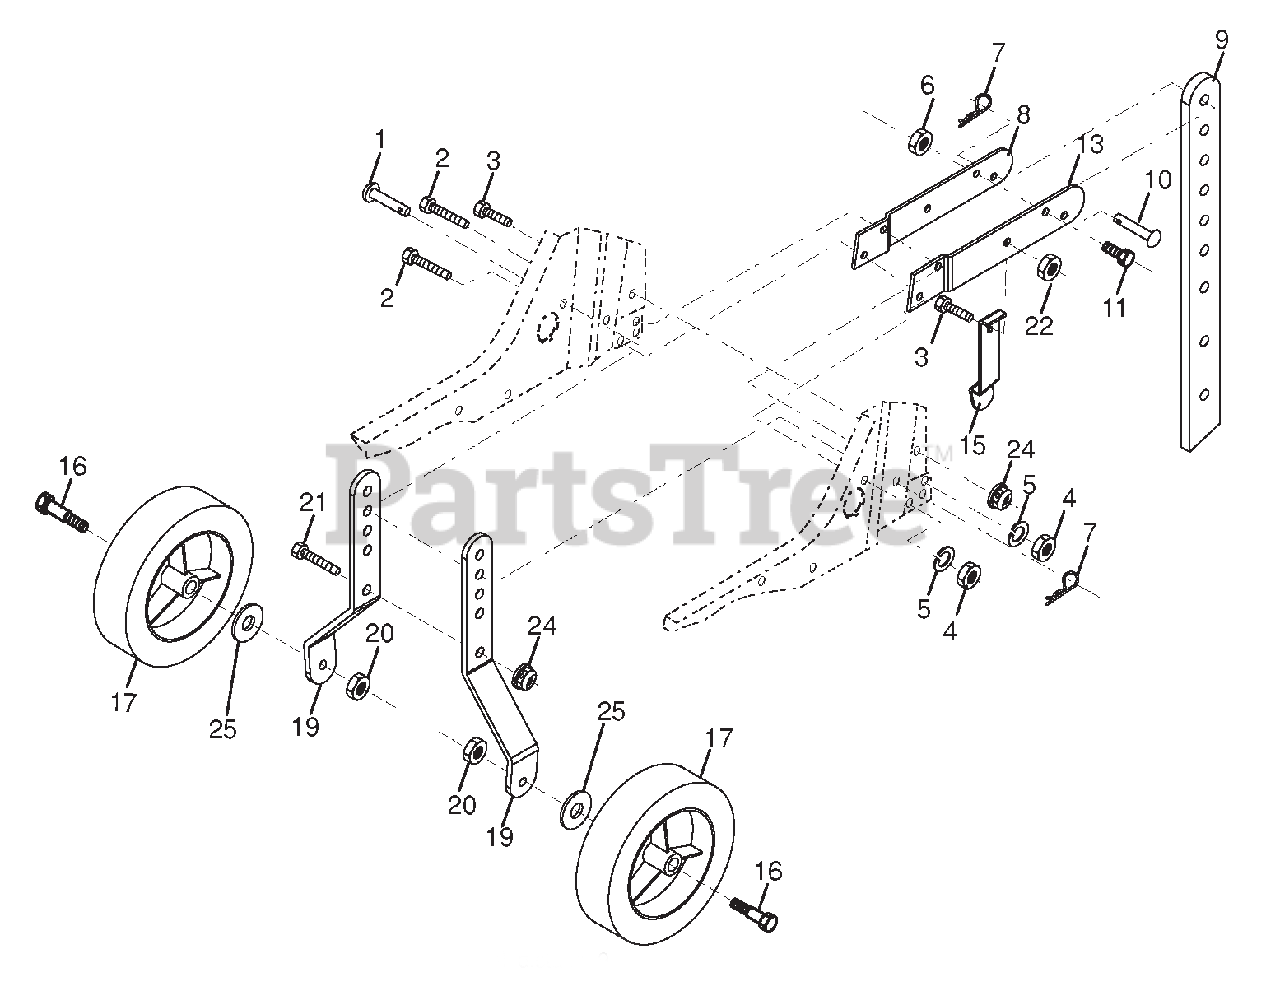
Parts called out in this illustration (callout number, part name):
1	Pin, Clevis
2	Bolt, Hex Head 5/16-18 x 1-1/4
3	Bolt, Hex Head 5/16-18 x 3/4
4	Nut, Hex 5/16-18
5	Washer, Lock 5/16
6	Locknut, Washer Insert 3/8-16
7	Clip, Hairpin
8	Support, Depth Stake, R.H.
9	Stake, Depth
10	Pin, Clevis
11	Bolt, Hex Head 3/8-16 x 1-3/4
13	Support, Depth Stake, L.H.
15	Spring, Stake
16	Bolt, Shoulder
19	Bracket, Wheel
20	Nut, Hex, Crownlock 3/8-16
21	Bolt, Hex Head 5/16-18 x 1
22	Locknut, Washer Insert 5/16-18
24	Nut, Hex, Flangelock
25	Washer, 17/32 x 7/8 x 16 Ga.
